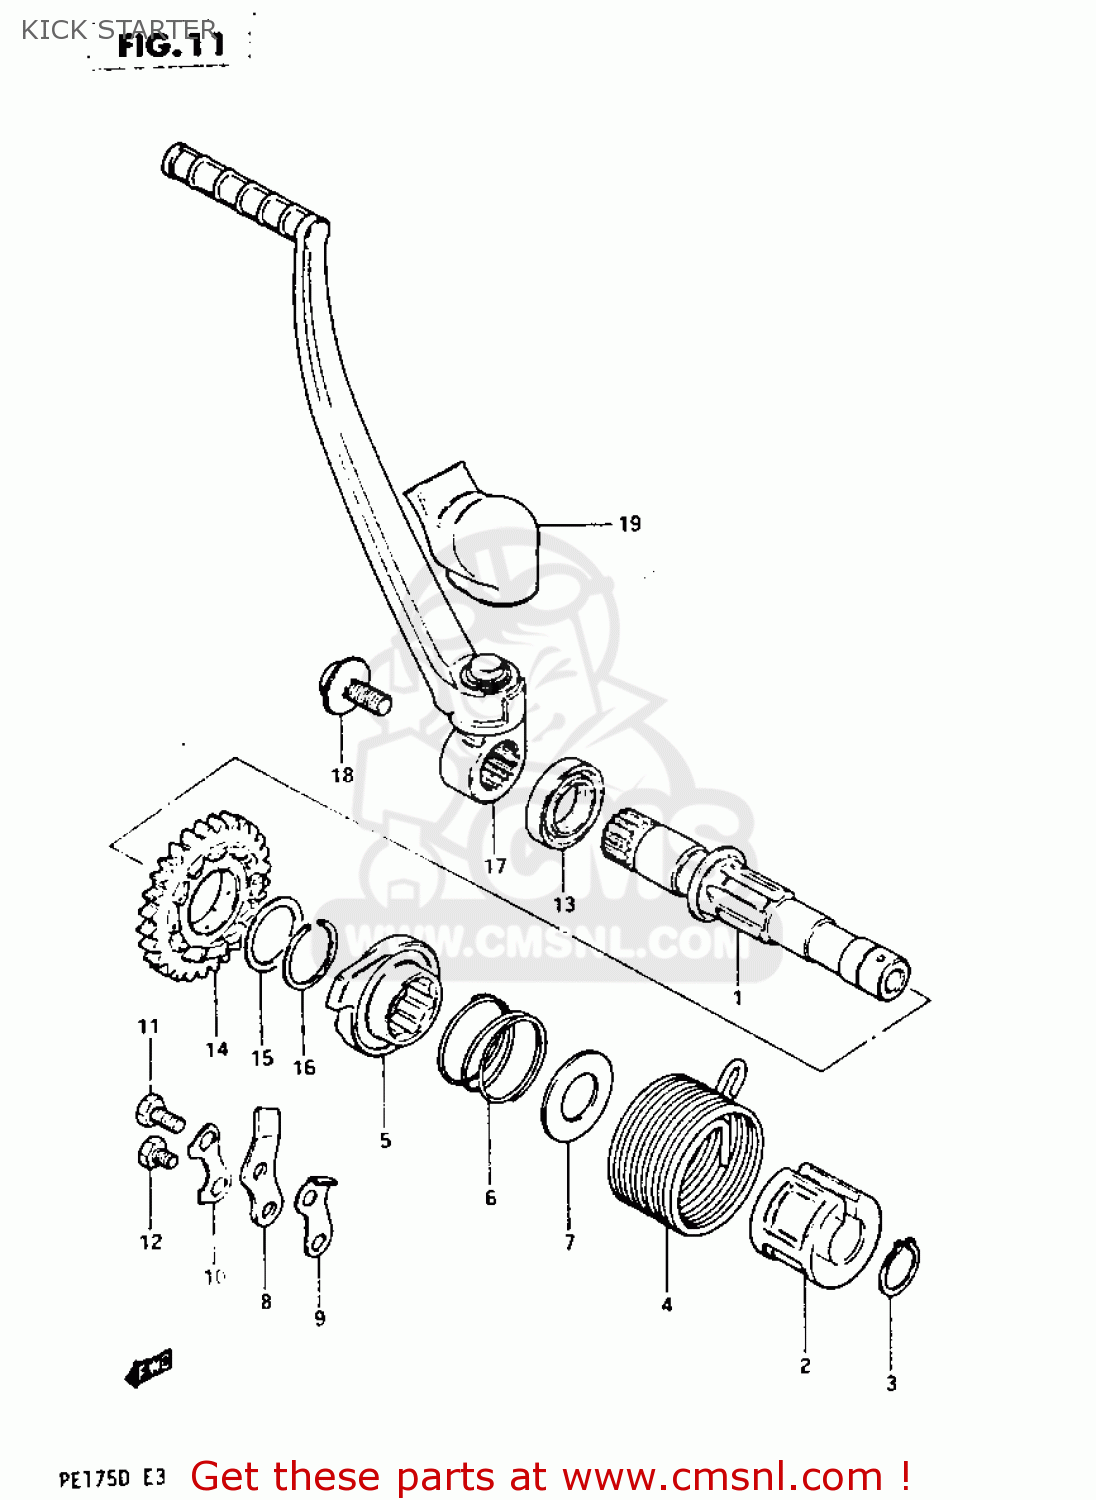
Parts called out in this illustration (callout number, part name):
1	SHAFT,KICK STARTER
2	GUIDE,KICK STARTER SFT SPRING
3	CIRCLIP
4	SPRING
5	STARTER,KICK
6	SPRING
7	WASHER
8	GUIDE,KICK STARTER
9	STOPPER,KICK STARTER
10	WASHER
11	BOLT
12	BOLT
13	SEAL,OIL(20X27X5)
14	GEAR,KICK STARTER DRIIVE
15	SHIM
16	CIRCLIP
17	LEVER ASSEMBLY,KICK STARTER
18	BOLT(8X14)
19	COVER,KICK STARTER LEVER JOINT
